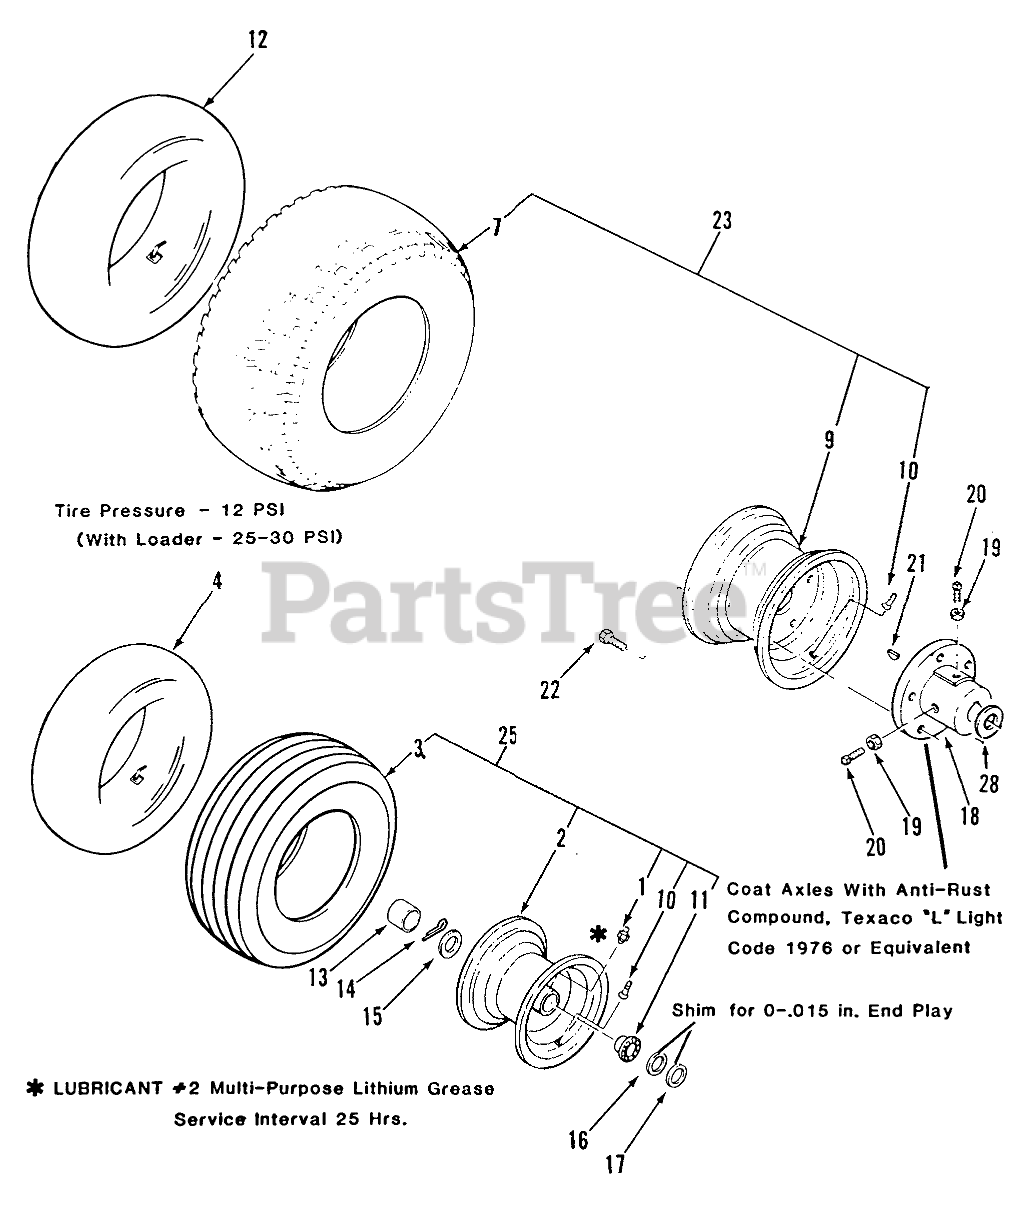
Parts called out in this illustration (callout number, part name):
1	ZERK-GREASE
2	Front Wheel (includes item 1, 10, 11)
3	TIRE15 X 6.00-6
7	TIRE 22 X 9.00-12
9	WHEEL
10	VALVE
11	BEARING-WHEEL
12	TUBE-INNER
13	HUB CAP-FLAT BLACK
14	COTTER PIN-4
15	WASHER-WHEEL
16	WASHER
17	WASHER-SHIM
18	Hub-Rear
19	Nut
20	Screw-Set
21	WOODRUFF KEY
22	Lug Nut
23	Rear Wheel & Tire Assy 312
25	Assy-Wheel & Tire Front
